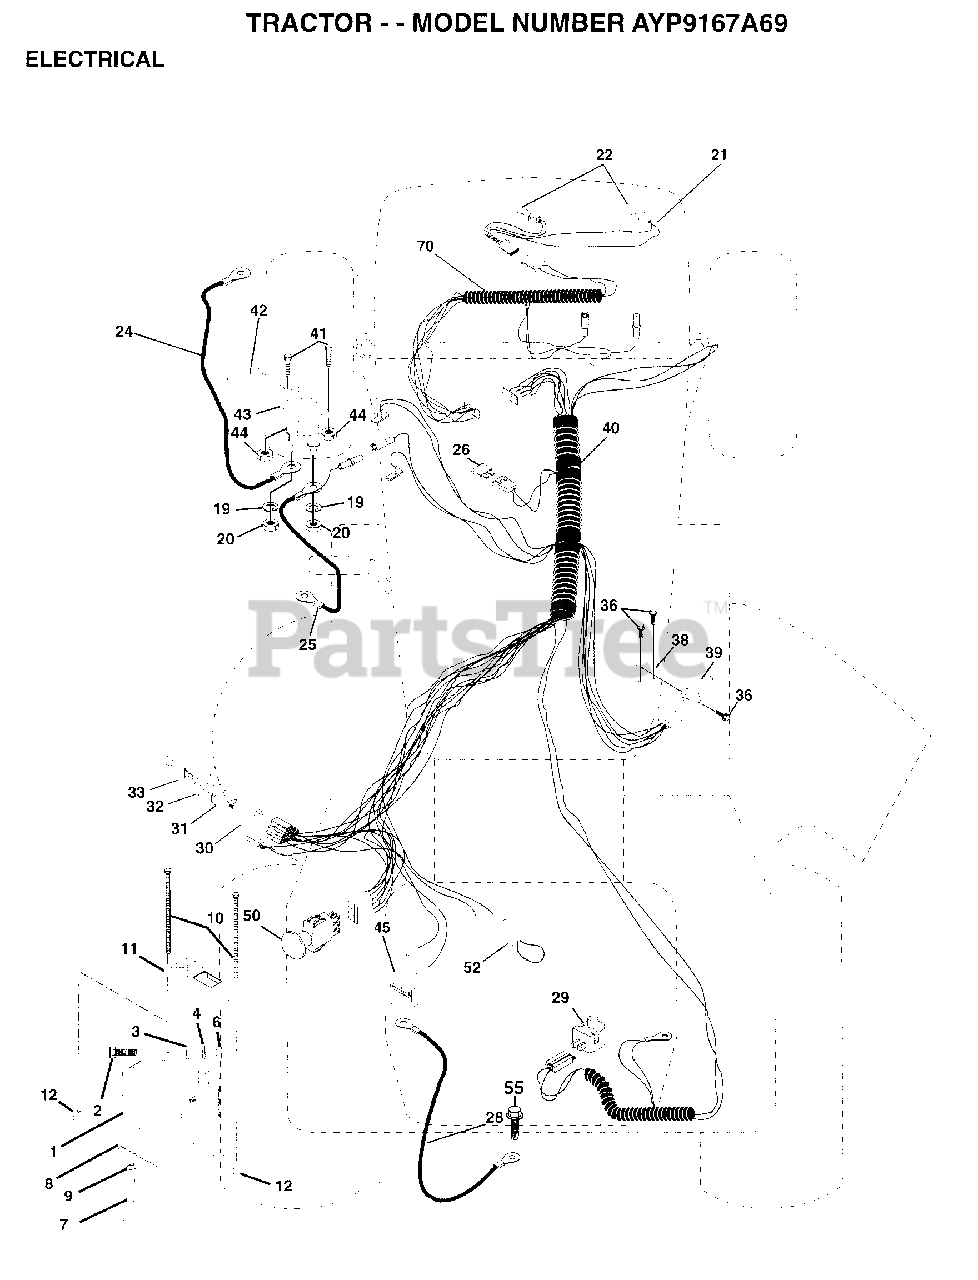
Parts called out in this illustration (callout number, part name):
2	BOLT LT
3	WASHER
4	LOCKWASHER
7	"DRAIN TU T, BATT"
8	"TRAY T, BATTERY"
9	HOSE CLAMP T
20	NUT
21	"HARNESS,LIGHT SOC"
22	HEADLAMP BULB
24	"CABLE T, BATTERY"
25	CABLE.6GA.22W/16W
26	FUSE HYT
28	CABLE.GRND.6GA.21
29	SWITCH SEAT
30	SWITCH IGN 4POS
31	NUT IGNITION
32	COVER KEY SWITCH
33	KEY
35	BRACKET LT
36	SCREW
38	BRACKET SWITCH IN
39	SWITCH INTERLOCKT
40	IGNITION HARNESS
41	BOLT HXHD FIN
44	NUT HXKEP 1/4X20
45	AMMETER
52	PROTECTION LOOP
55	SCREW LT
70	HARNESS.ENG.LT.
